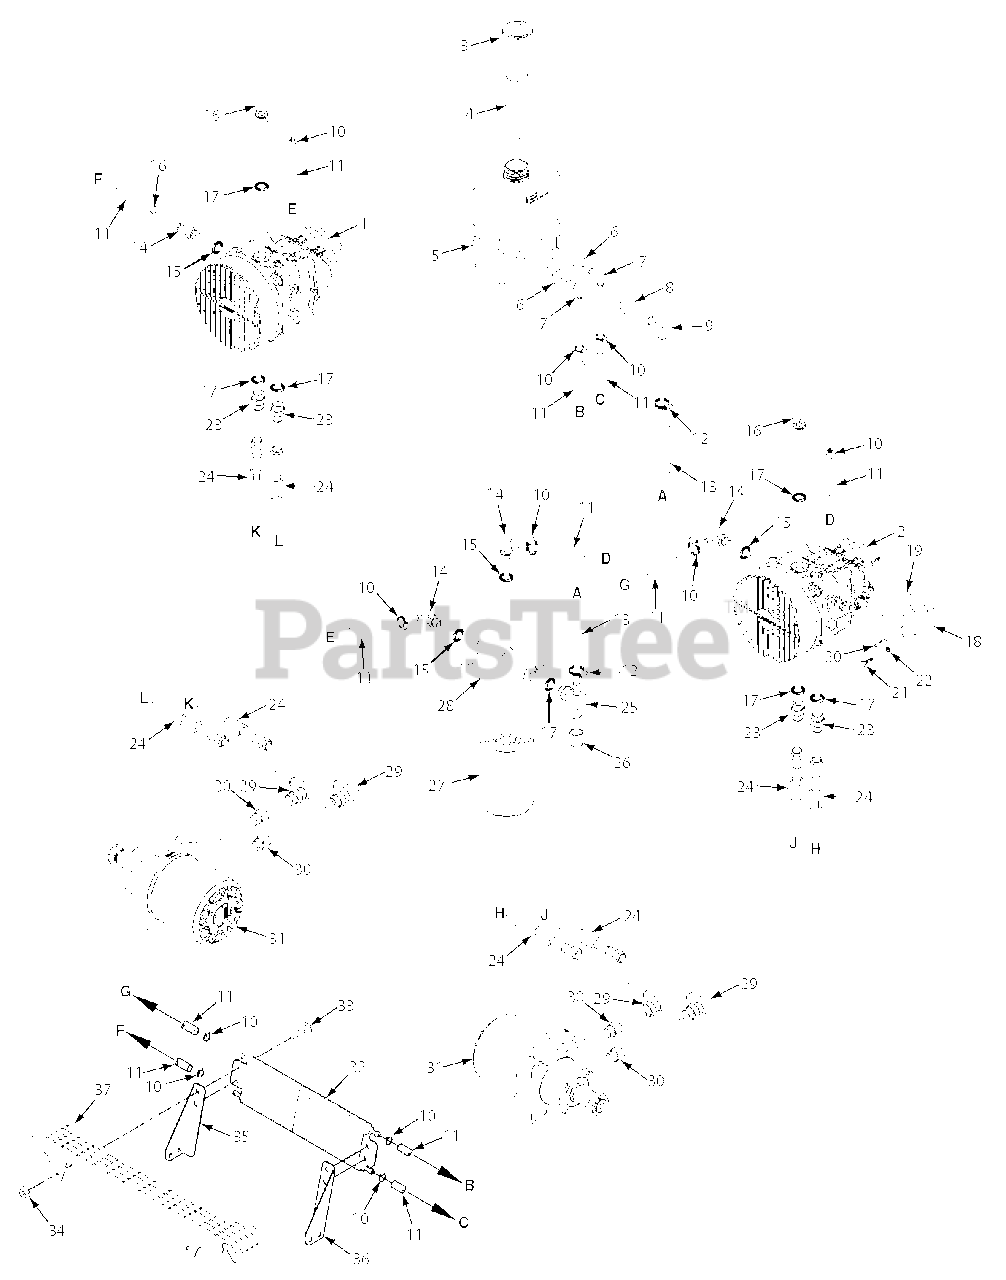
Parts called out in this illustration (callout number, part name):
1	Pump, RH w/Fan
2	Pump, LH, w/Fan
3	Cap, Hydraulic Tank
4	Insert, Filler Neck
5	Hydraulic Tank Assy., STTII
6	Bushing, .56 Dia. Viton
7	Fitting, 90 Degree - .38 Hose
8	Bushing, .78 Dia Viton
9	Fitting, 90 Degree - .50 Hose
10	Clamp, Hose
11	Hose, 3/8 Pushlock (order by inch)
12	Clamp, Hose
13	Hose, 1/2 Pushlock (order by inch)
14	Elbow, 90 Degree - 9/16 O-Ring
15	O-Ring, 9/16-18 Thread
16	Elbow, 90 Degree - 3/4 O-Ring
17	O-Ring, 3/4-16 Thread
18	Plate, Pump Control Clamp
19	Block, RH Pump Control
19	Block, LH Pump Control
20	Pin, 7/32 x 1"
21	Bolt, Hex Head 1/4-20 x 1-1/2"
22	Lockwasher, 1/4
23	Fitting, Union 3/4-16 JIC X O-Ring
24	Hose Assembly
25	Tee Fitting, 3/4 - O-Ring
26	Cap, JIC
27	Filter, Spin-On
28	Filter Head Assembly
29	Elbow, 90 Degree - 5/8 Tube
30	O-Ring Bushing, 5/8 Tube
31	Wheel Motor, Parker TG - 18ci.
32	Cooler, Transmission
33	Bolt, Carriage 1/4-20 x 1/2
34	Nut, Serrated Flange 1/4-20
35	Mounting Bracket, Cooler - RH
36	Mounting Bracket, Cooler - LH
37	Screen Guard, Kohler EFI
37	Screen Guard, Briggs & Stratton 35BV
